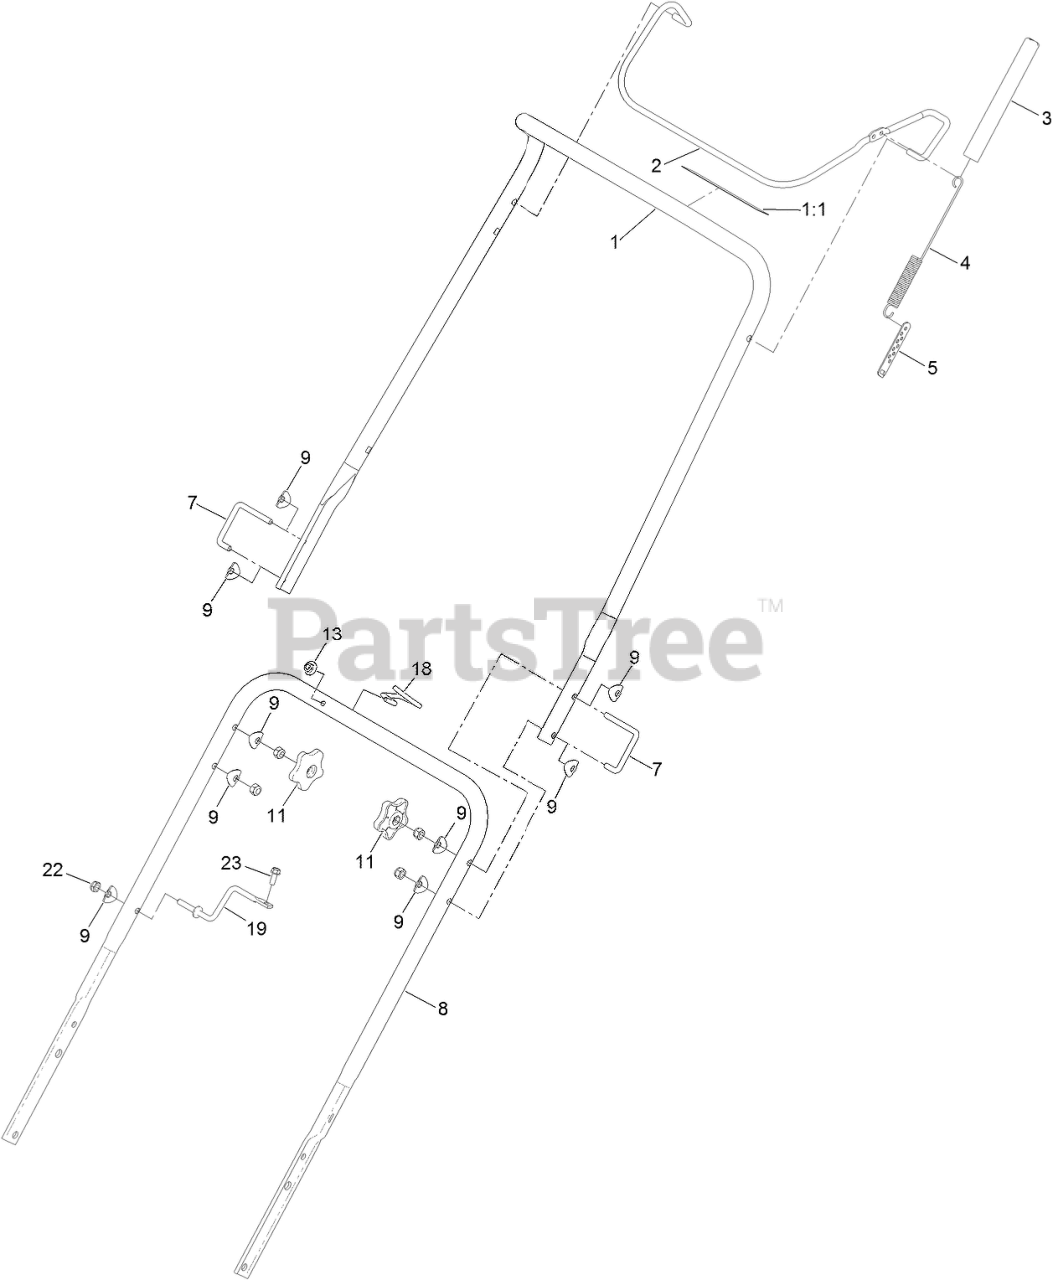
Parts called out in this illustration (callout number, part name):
1	UPPER HANDLE ASM
1:1	DECAL-DRIVE, ROTOR
2	BAIL-CONTROL
3	COVER-SPRING
4	SPRING-EXTENSION, CLUTCH
5	ADJUSTER-CLUTCH CABLE
7	LOCK-HANDLE
8	HANDLE-LOWER
9	WASHER
11	KNOB-HANDLE
13	NUT-HF
18	GUIDE-ROPE
19	SUPPORT-BOX, SWITCH
22	NUT-LOCK, NI
23	SCREW-HWH
